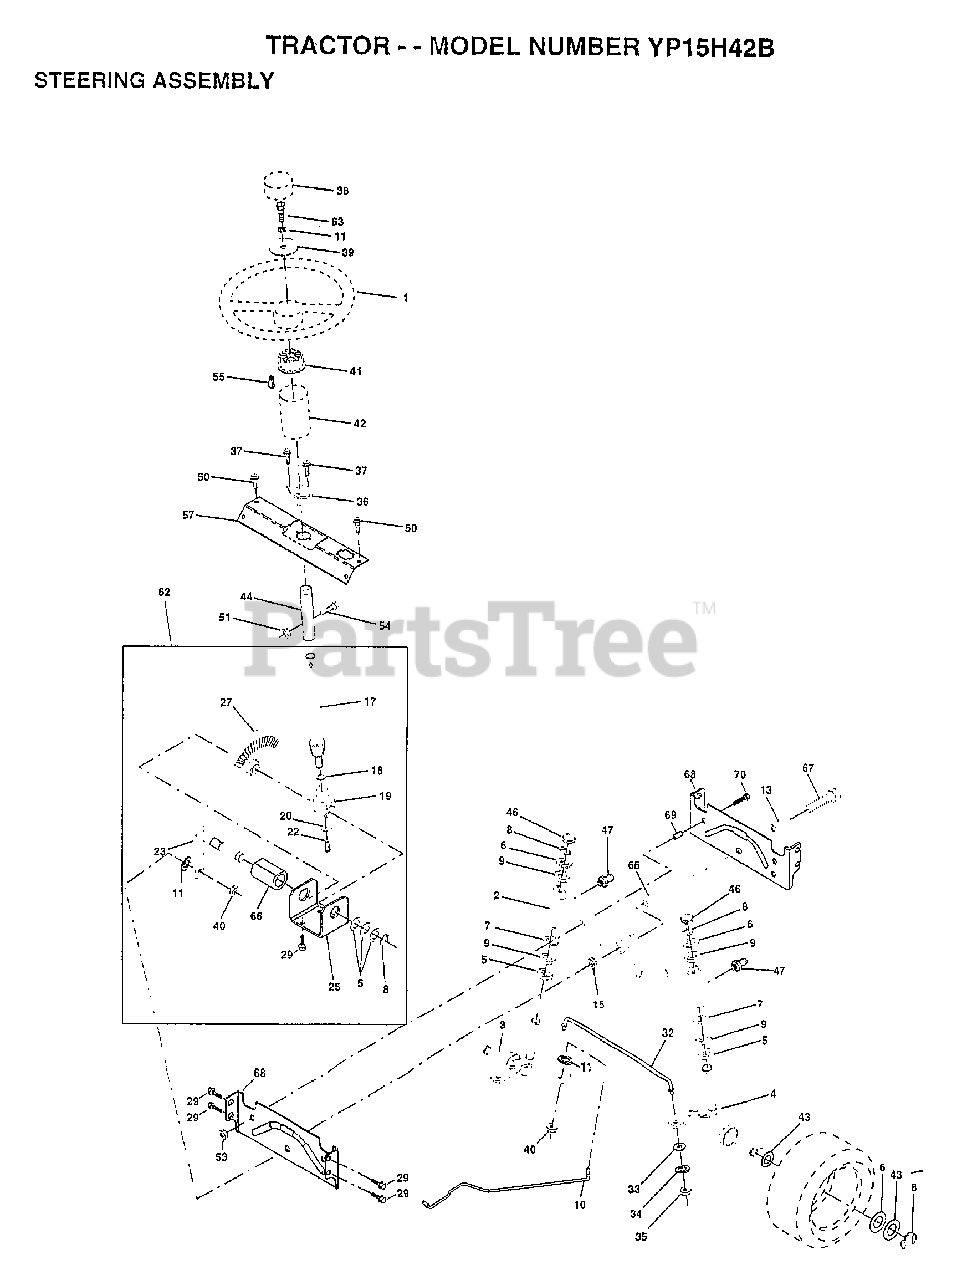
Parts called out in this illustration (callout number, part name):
2	AXLE ASM
3	SPINDLE.ASM.LH
4	"SPINDLE ASM,RH"
5	WASHER .T
6	WASHER
7	WASHER
8	RING
9	COL. SRTG. BEAR.
10	DRAGLINK-STAMPED
11	LOCKWASHER
13	BEARING AXLE
15	"NUT-LOC,FLANGE LT"
17	SHAFT ASM STEERIN
18	THRUST WASHER
19	SUPPORT.SHAFT
22	SCREW HEX SOC1/4-
25	BRKT-STEERING
27	GEAR SECTOR
29	SCREW
32	ROD.TIE.19.75
33	WASHER 11/32 X 3/4 /16 GA
34	LOCKWASHER
35	NUT.LOCK.5/16-24
36	BUSHING.STR.623
37	"SCREW-TT,10-32 FL"
38	"INSERT,STR WHEEL"
39	WASHER T
40	GRIPCO NUT
41	ADAPTER LT
42	BOOT SHAFT STEER
43	WASHER
44	SHAFT EXT STEERIN
46	CAP
47	ZERK M
50	SCREW HEX CRT
51	NUT
54	BOLT
55	CLIP TINNERMAN
57	SUPPORT SHAFT STR
62	KIT STEERING ASM
63	BOLT
65	SPACER AXLE
66	"BEARING-ARM,PITMA"
67	BOLT
68	BRACE AXLE
69	"SPACER BRCAE,AXLE"
70	BOLT FIN HEX 3/8-16 UNC X 2-1/4
